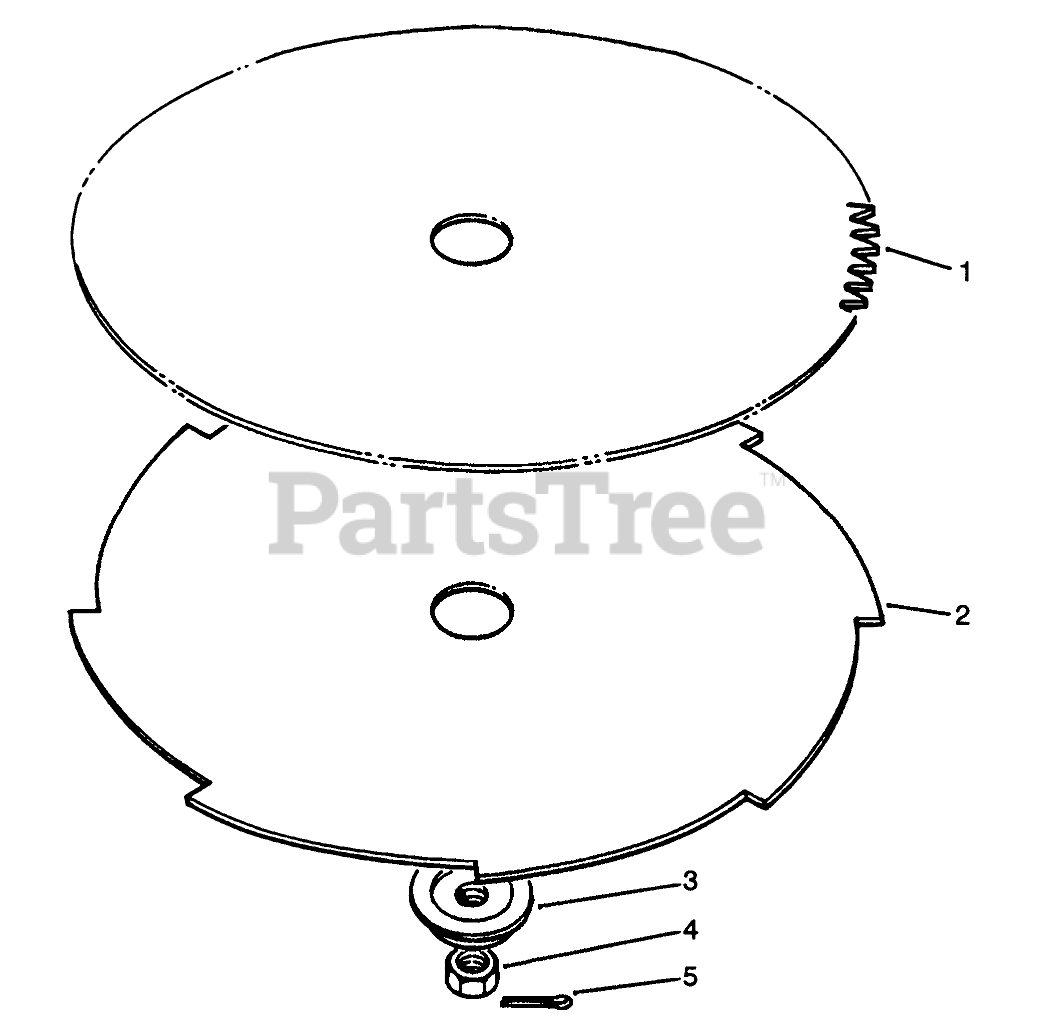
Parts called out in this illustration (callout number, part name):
1	SAW BLD PKG(8", 80T)
2	BRUSH BLD PKG(8",8T)
3	Adapter-Blade
5	1/16 X 1 LG COTTER PIN
